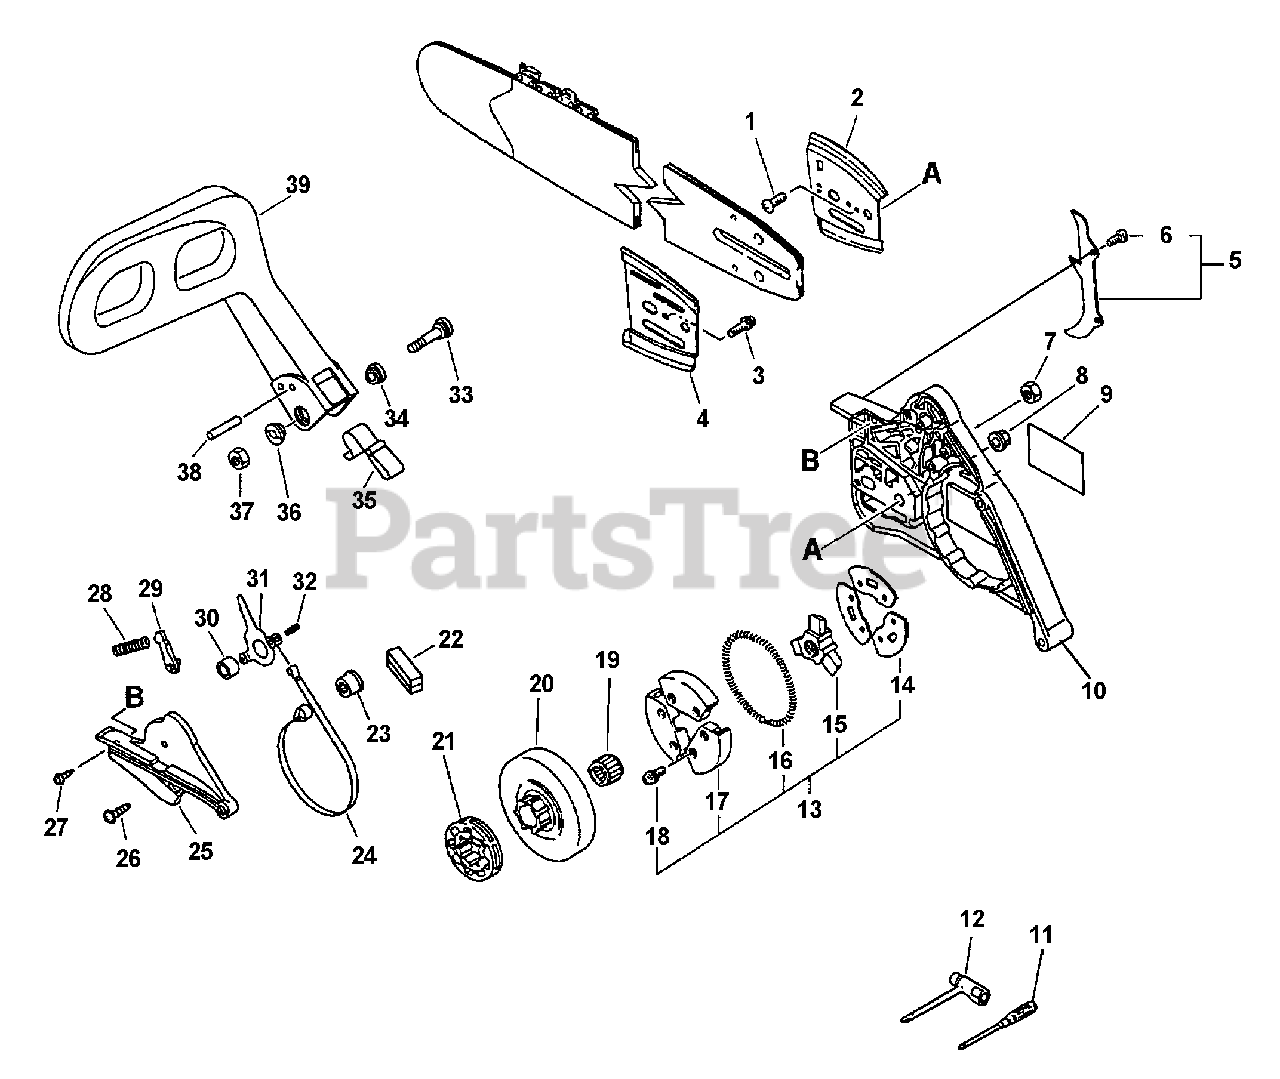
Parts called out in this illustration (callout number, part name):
1	SCREW 3×6
2	PLATE, GUIDE - OUTER
3	SCREW 4×8
4	PLATE, GUIDE - INNER
5	SPIKED BUMPER KIT
7	NUT 3 MM
8	NUT, FLANGE M8×1.25
9	LABEL, ECHO
10	GUARD, SPROCKET
11	SCREWDRIVER, PHILLIPS
12	T-WRENCH 13×19×180
13	CLUTCH ASSY
14	PLATE, CLUTCH
15	HUB, CLUTCH
16	SPRING, CLUTCH
17	CLUTCH SHOE SET
18	BOLT 4×6
19	BEARING, NEEDLE
20	DRUM, CLUTCH
21	SPROCKET, RIM 3/8"×7T
22	SEAL, BRAKE
23	ADJUSTER, BRAKE
24	BAND, BRAKE
25	COVER, BRAKE
26	SCREW 3×18
27	SCREW 4×12
28	SPRING, BRAKE
29	STOPPER, BRAKE
30	SPACER 8×12×9
31	LEVER, BRAKE
32	PIN, SPRING 4×8.8
33	SCREW 5×35
34	COLLAR 5
35	SPRING, RETURN
36	COLLAR 5.3×10×13×L5
37	NUT, LOCK M5
38	PIN 3.5×26
39	LEVER, BRAKE
